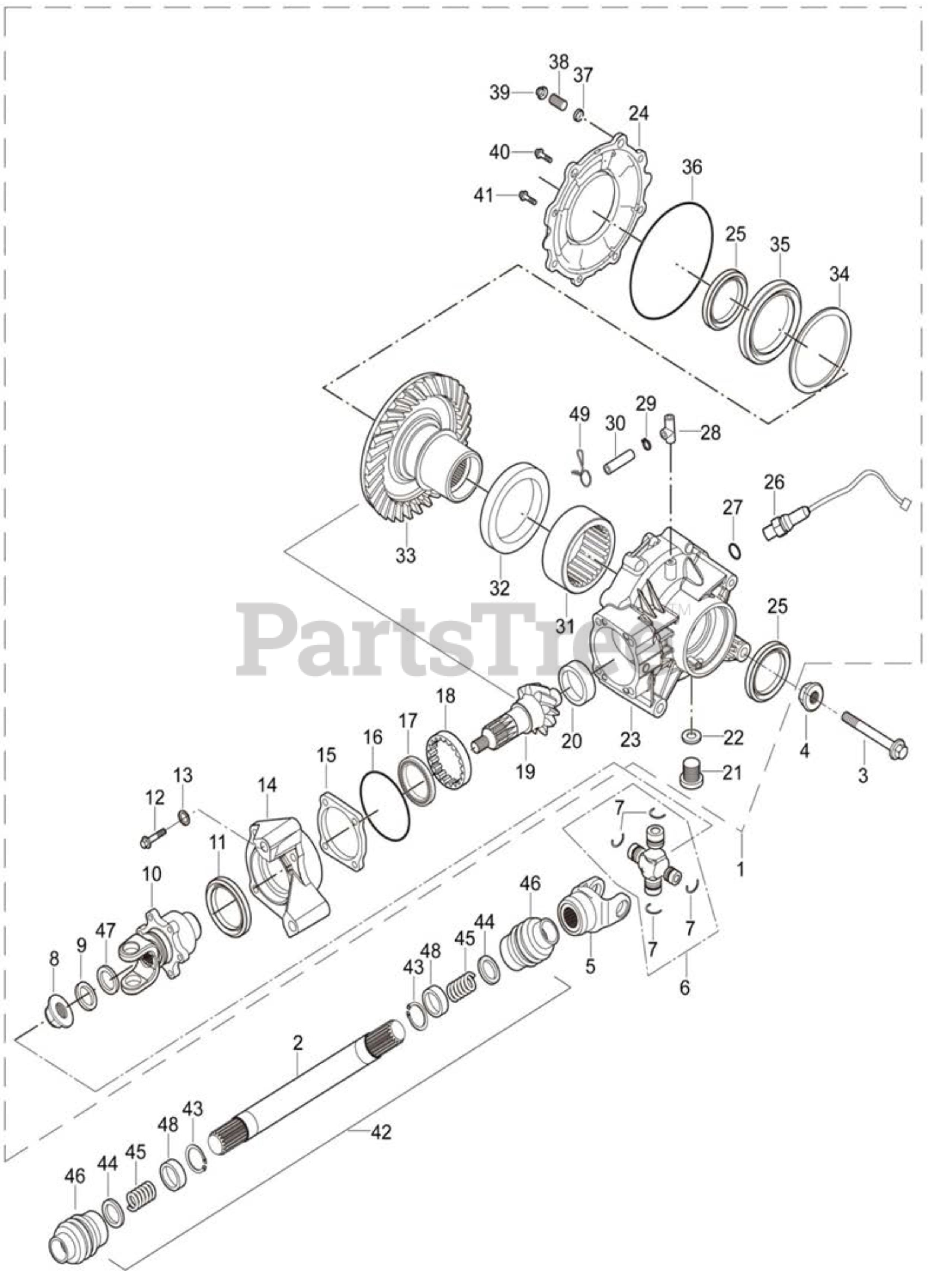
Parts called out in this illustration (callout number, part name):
1	Rear Diff. Assy
2	Rear Transmission shaft K
3	Hexagon Flange Bolt M10X1.25X120
4	Hexagon Flange Self-Lock Nuts M10x1.25
6	Criss-CrossShaft
8	Flange bolt M12X1.25
9	Driving gear Washer
11	Oil seal 61X35X9
12	Hexagon flange bolts M8X35
13	Flat waher 8
14	Brake caliper mounting case
15	Adjusting washer 78X93X0.1
16	O-type ring 71X2.65
17	Bearing 6305
18	Clamping bush
19	Rear differencial driving gear
20	Needle bearing 22X30X13
21	Flange bolt M10X1.25X16
22	O-type rubber ring 8.5X1.5
23	Rear Diff. Case
24	Rear Diff. Cover
25	Output oil seal 70X90X9
26	Speed Sensor Assy.
27	O-ring 18X2.65
28	Rear diff air fitting
29	Spring clamp C
30	Air vent line
31	Needle bearing 55X67X20
32	Adjusting washer 55.2X66.8X1.7
33	Rear diff driven gear
34	Adjusting washer 86X100X0.1
35	Bearing 16017
36	O-ring 3.1X150
37	Copper washer 8.2X1
38	Flat screw M8X45
39	Flange nut M8
40	Flange bolt M8X25
41	Flange bolt M10X1.25X25
43	Spring clip 25
44	Rear axle Washer B
45	Rear axle Spring B
46	Rear axle rubber boot C
47	Driving gear rubber washer
